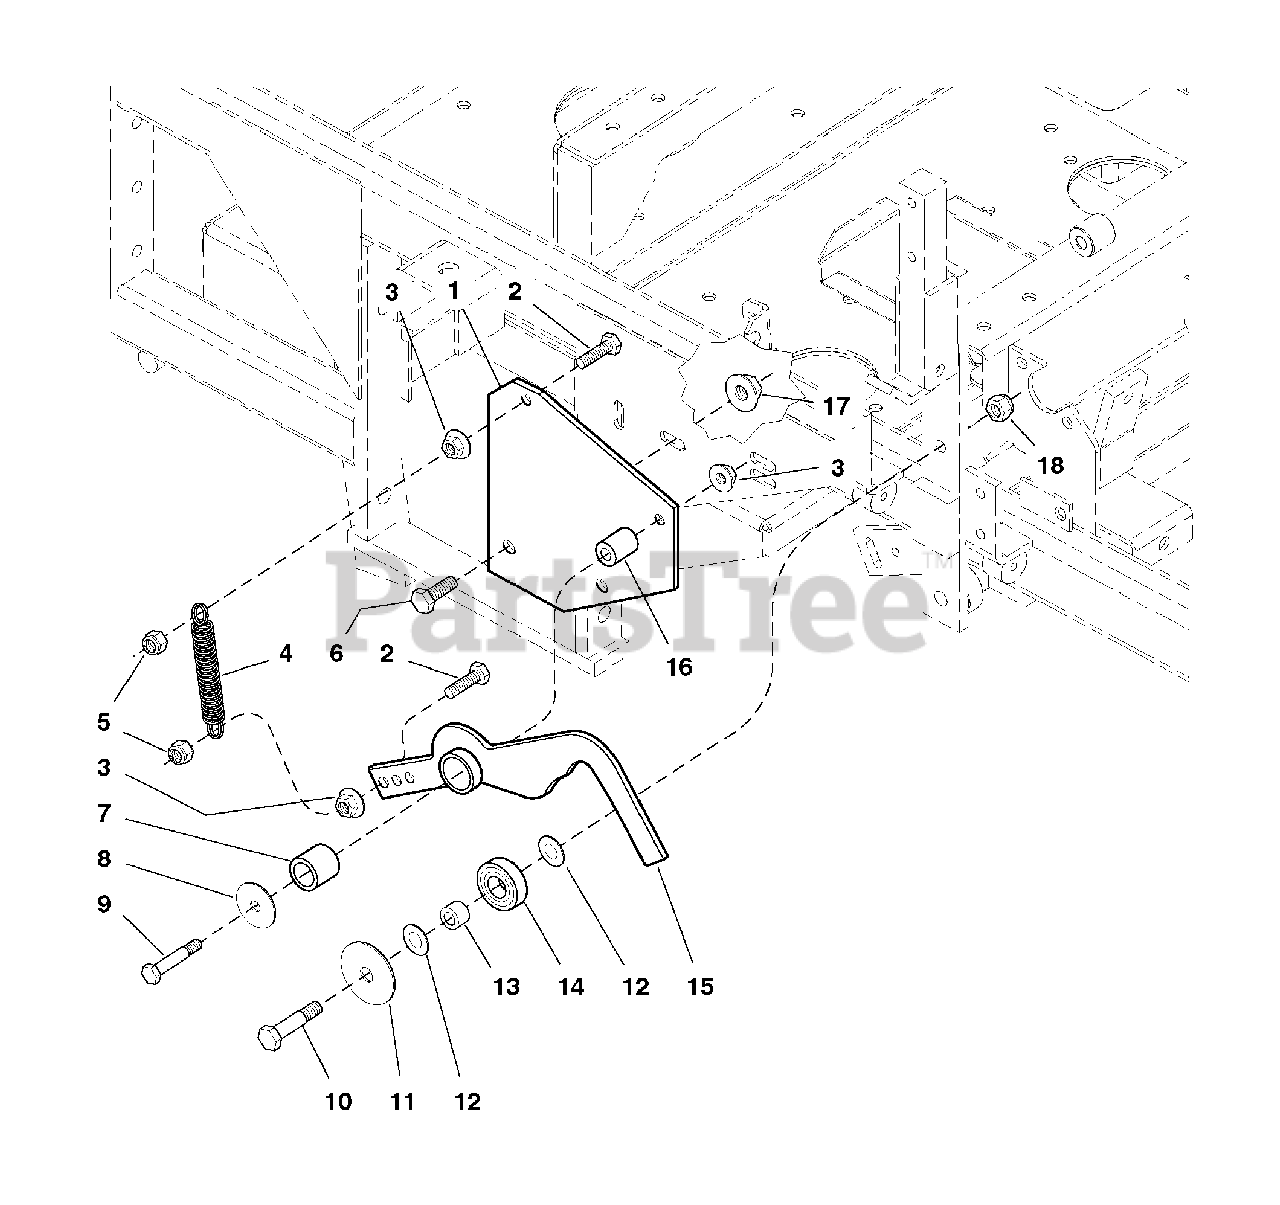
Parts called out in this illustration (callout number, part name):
1	NEUTRAL RETURN MOUNT PLATE
2	CAPSCREW, Hex Hd, 5/16-18 x 1-1/4 TFL
3	NUT, Hex, Serrated Flange, 5/16-18
4	SPRING, Extension
5	NUT, Hex, Nylon Lock, 5/16-18
6	CAPSCREW, Hex Hd, 3/8-16 x 3/4
7	BUSHING, Brass
8	WASHER, 5/16 Fender
9	CAPSCREW, Hex Hd, 5/16-18 x 1-3/4
10	CAPSCREW, Hex Hd, 3/8-16 x 1-3/4
11	WASHER, 3/8 x 2
12	WASHER, 3/8
13	INSERT, Bearing
14	BEARING, BALL 11/16X1-9/16X15/32
15	NEUTRAL RETURN LEVER
16	SPACER, Pivot
17	NUT, Hex, Serrated Flange, 3/8-16
18	NUT, Hex, Nylon Lock, 3/8-16
